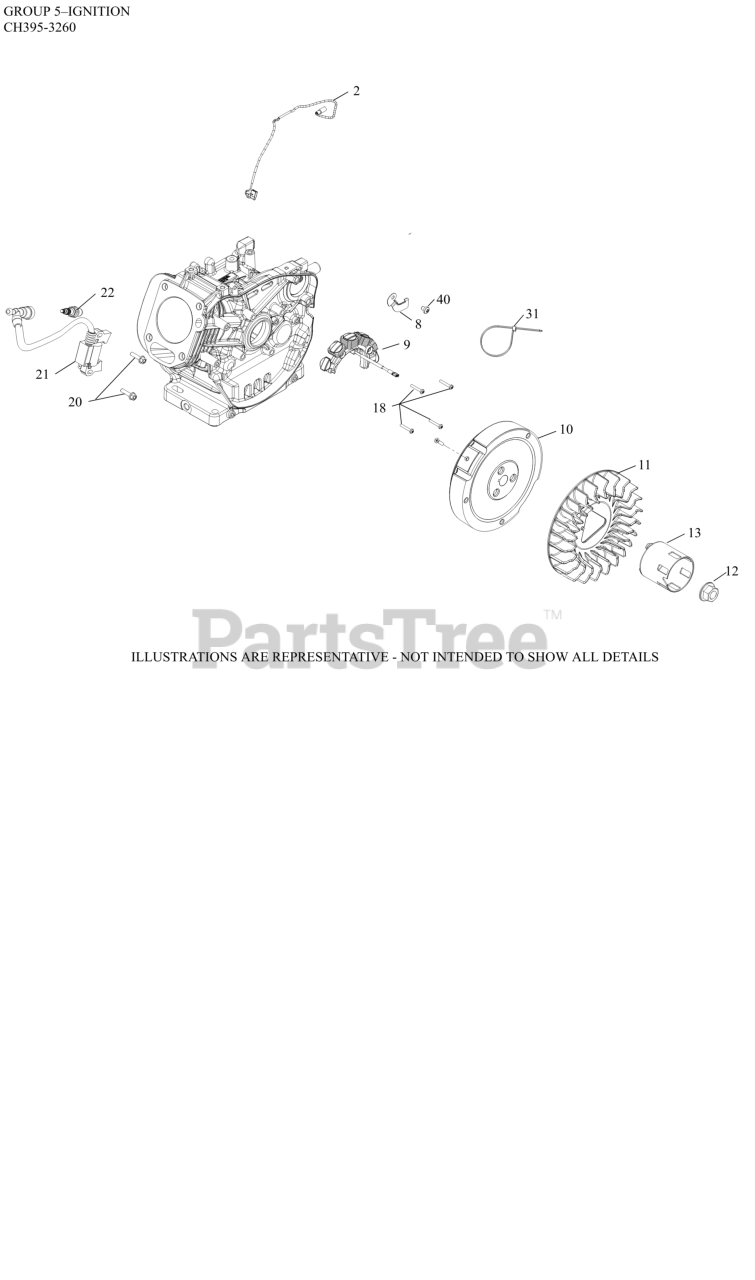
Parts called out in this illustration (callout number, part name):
2	LEAD, GROUND TO KILL
8	BRACKET, STATOR WIRE
9	STATOR ASSEMBLY, 3A
10	FLYWHEEL ASSY ELECTRIC START (CH395)
11	FAN, FLYWHEEL
12	NUT, FLYWHEEL
13	CUP, STARTER DRIVE
18	SCREW, STATOR MOUNTING
20	SCREW, M6 X 25-(#25086436S)
21	MODULE, SPARK PLUG ASSY
22	SPARK PLUG
40	SCREW, COIL BRACKET
